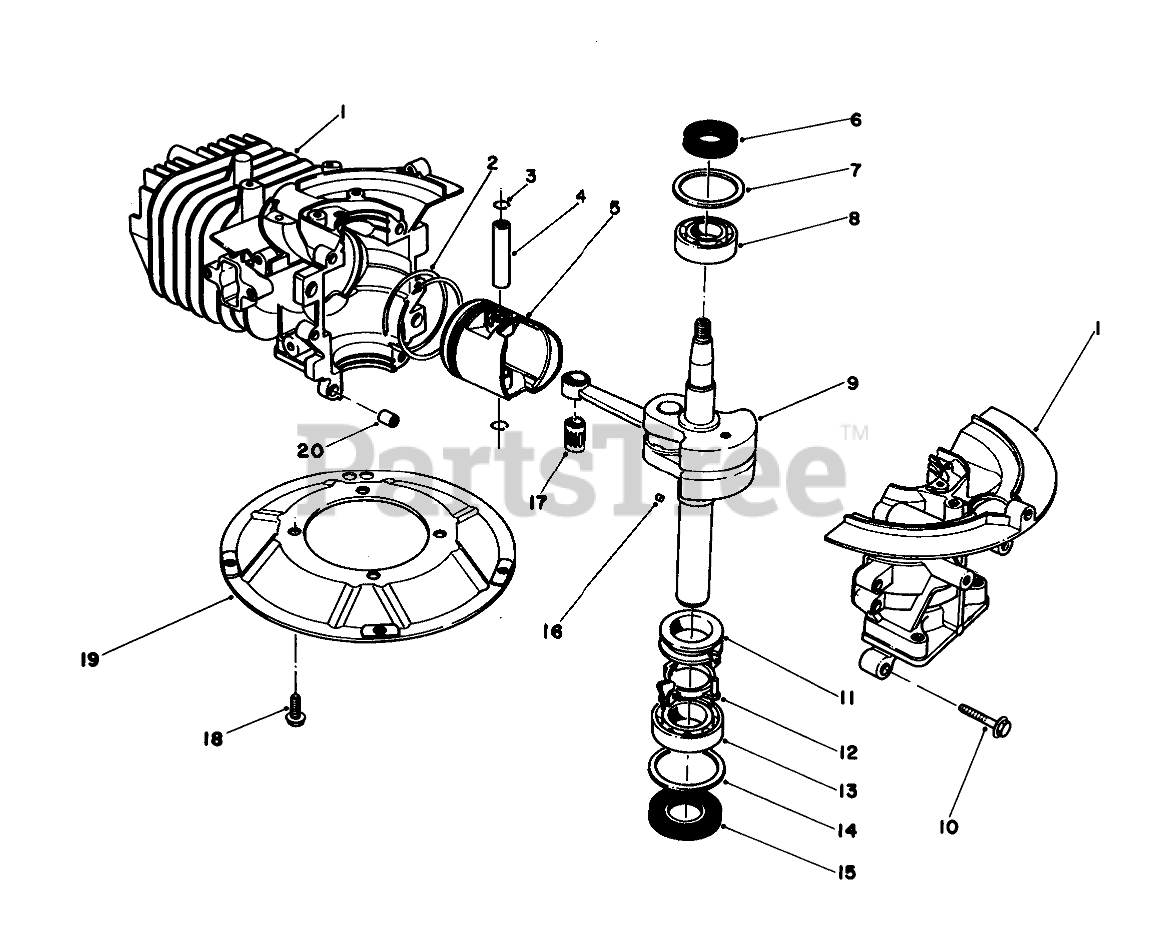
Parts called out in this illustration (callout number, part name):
1	Crankcase-Cylinder Assy.
2	RING SET
4	PIN-PISTON
5	Piston
6	OIL SEAL
7	WASHER-UPPER
8	BEARING-UPPER
9	CRANKSHAFT ASM
11	SPACER
12	BRACKET
13	LOWER BRG
14	WASHER-LOWER
15	SEAL-OIL
17	BEARING
19	Plate-Mounting
